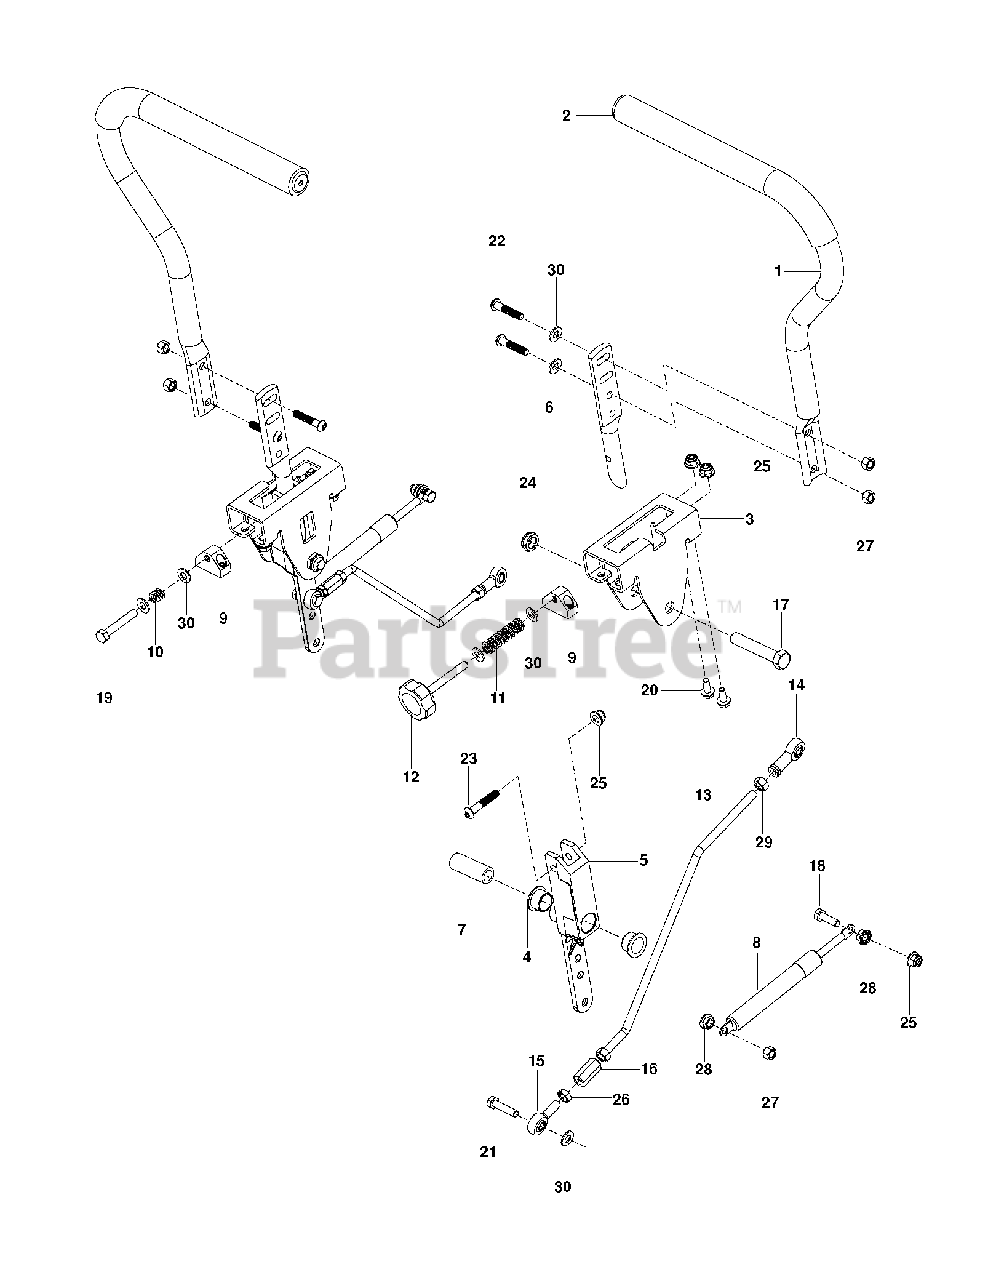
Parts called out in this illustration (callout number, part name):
1	CONTROL.TUBE.RZ (2 2)
2	GRIP, DRIVE LEVER
3	BRACKET.CONTROL.NARROWSLOT.BLK
4	BEARING, FLANGE
5	LEVER CONTROL PIVOT
6	LEVER.HANDLE MOUNT
7	SPACER, PIVOT CONTROL
9	BLOCK TRACKING CONTROL ZTR
11	SPRING COMPRESSION 2.0
13	ROD MOTION CONTROL
14	RH ROD END
15	RB ROD.END.LH
16	ROD END COUPLER
17	HCS 1/2-13 X 2-3/4 GD 5 ZD
18	BOLT.FIN.HEX.5/16-18UNC X 1.00
19	HEX BOLT
20	HHFS 5/16-18 X 3/4
22	SCREW BUTTONHEAD 5/16-18X1-1/2
23	SCREW 5/16-18 X 1 3/4 BTN-HD
24	NUT 1/2-13 HEX JM NYL
25	5/16-18 NYLOC FLANGE NUT
26	NUT 5/16F LEFTHAND
27	NUT.71038.31-18.HEX.NYLOCK
28	NUT 5/16C WHIZ
30	WASHER
